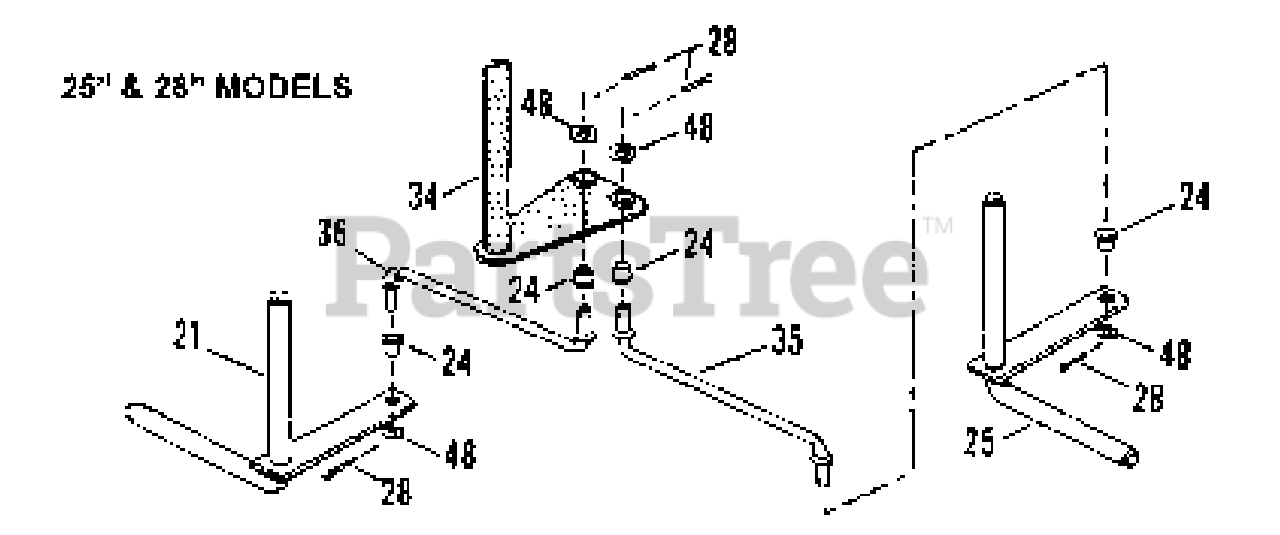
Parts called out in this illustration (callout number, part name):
21	PIN, Narrow King (Right Side)
24	BUSHING, Nylon
25	PIN, Narrow King (Left Side)
28	COTTER-PIN, 5/32 x 1"
34	SHAFT, Steering (Narrow Front End)
35	TIE-ROD, Left Side (25" & 28" Models)
36	TIE-ROD, Right Side (25" & 28" Models)
48	WASHER, 3/8" Flat
